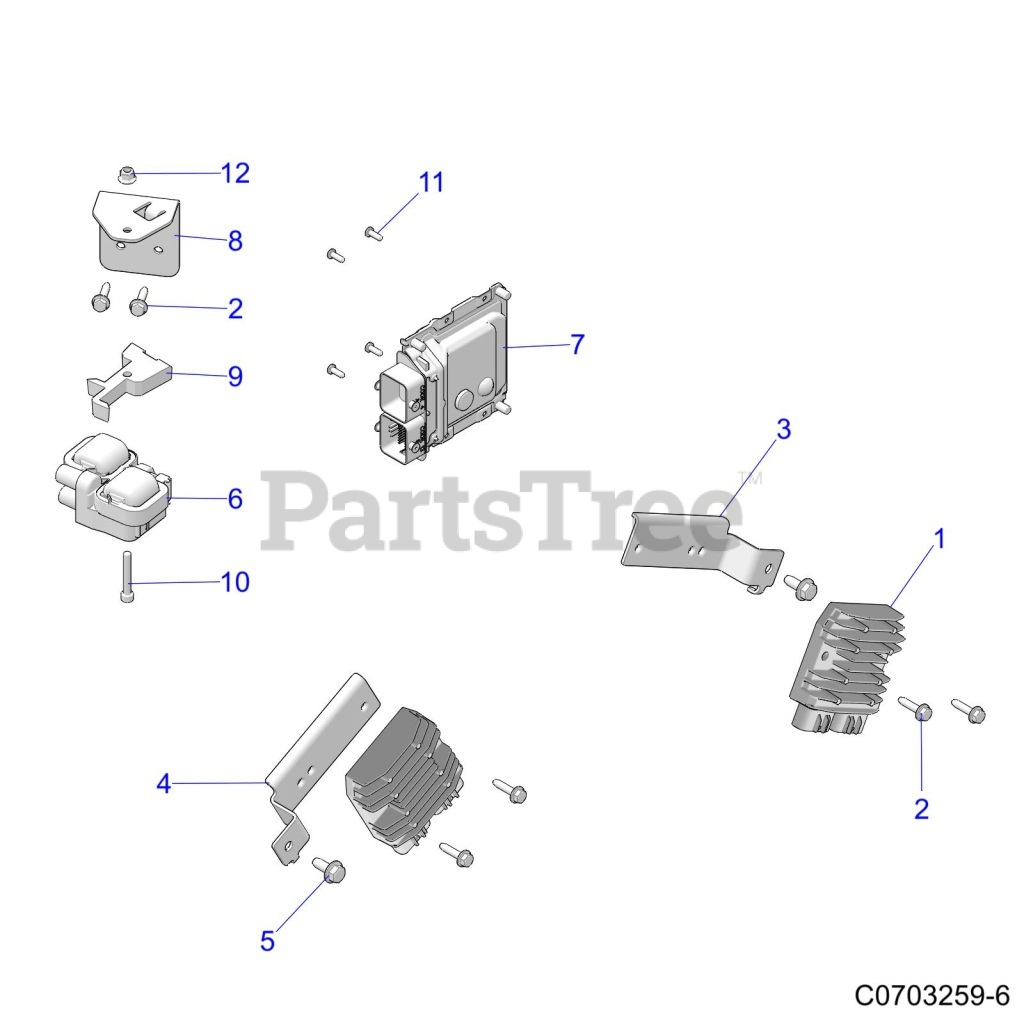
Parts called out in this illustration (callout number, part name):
1	REGULATOR-3PH,35A,SERIES,105C
2	SCR-TFHFL-M6X1.0X25,ZTC
3	BRKT-MOUNT,REG
4	BRKT-MOUNT,REG
5	BOLT-M8X1.25X20,HXFLG,TAP/R-OD
6	COIL-EFI
7	ECM-NO START,ME17
8	BRKT-COIL,MOUNT
9	SPACER-COIL MOUNT
10	SCR-M6X1.0X40,HX/SOC/CP-B
11	SCR-#10X1/2-HI/LO-PN-T25,TRX-M
12	NUT-M6 FLANGE,NYLOK
